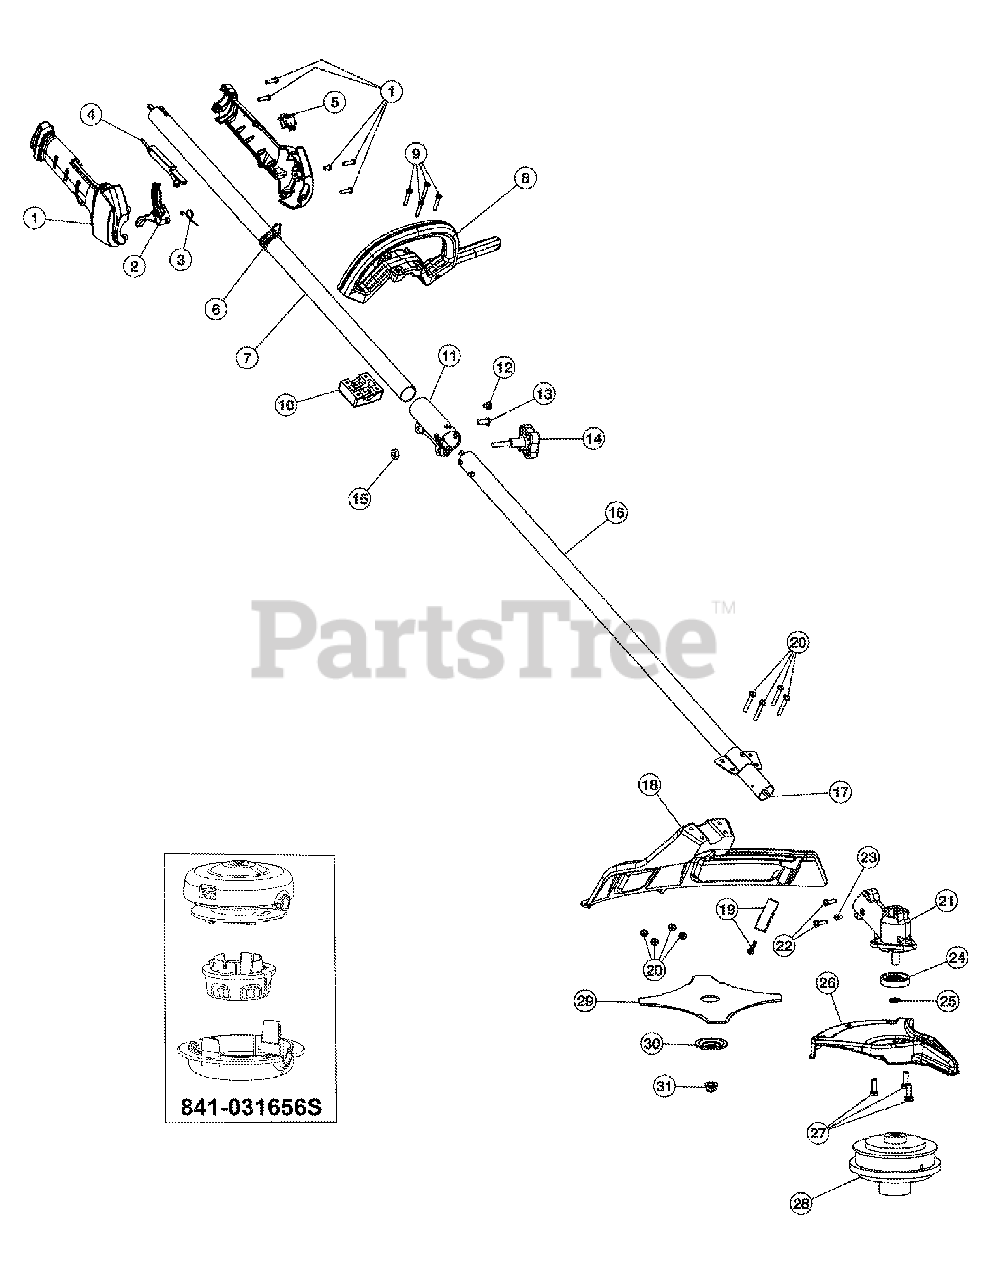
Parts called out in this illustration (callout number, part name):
1	Throttle Housing Assembly (includes 2 - 5)
2	Throttle Trigger
4	Throttle Lock-out
6	Shoulder Strap Clip
7	Upper Drive Shaft Housing Assembly
8	D-Handle Assembly (includes 9 & 10)
9	Handle Base
11	Split Boom Coupler (includes 12 - 15)
12	Coupler Anti-Rotation Screw
14	Adjustment Knob
15	Knob Retaining Nut
16	Lower Drive Shaft Housing Assembly (includes 17)
17	Lower Flexible Drive Shaft
18	Shield Assembly (includes 19)
19	Blade Assembly
20	Shield Mounting Screw & Nut
22	Gearbox Mounting Hardware
23	Anti-Rotation Screw
24	Blade Driver
26	Blade Shield
27	Blade Shield Mounting Hardware
28	Cutting Head Assembly
29	4-Tooth Blade
30	Retaining Washer
31	Nut
841-031656S	Cutting Head Assembly
